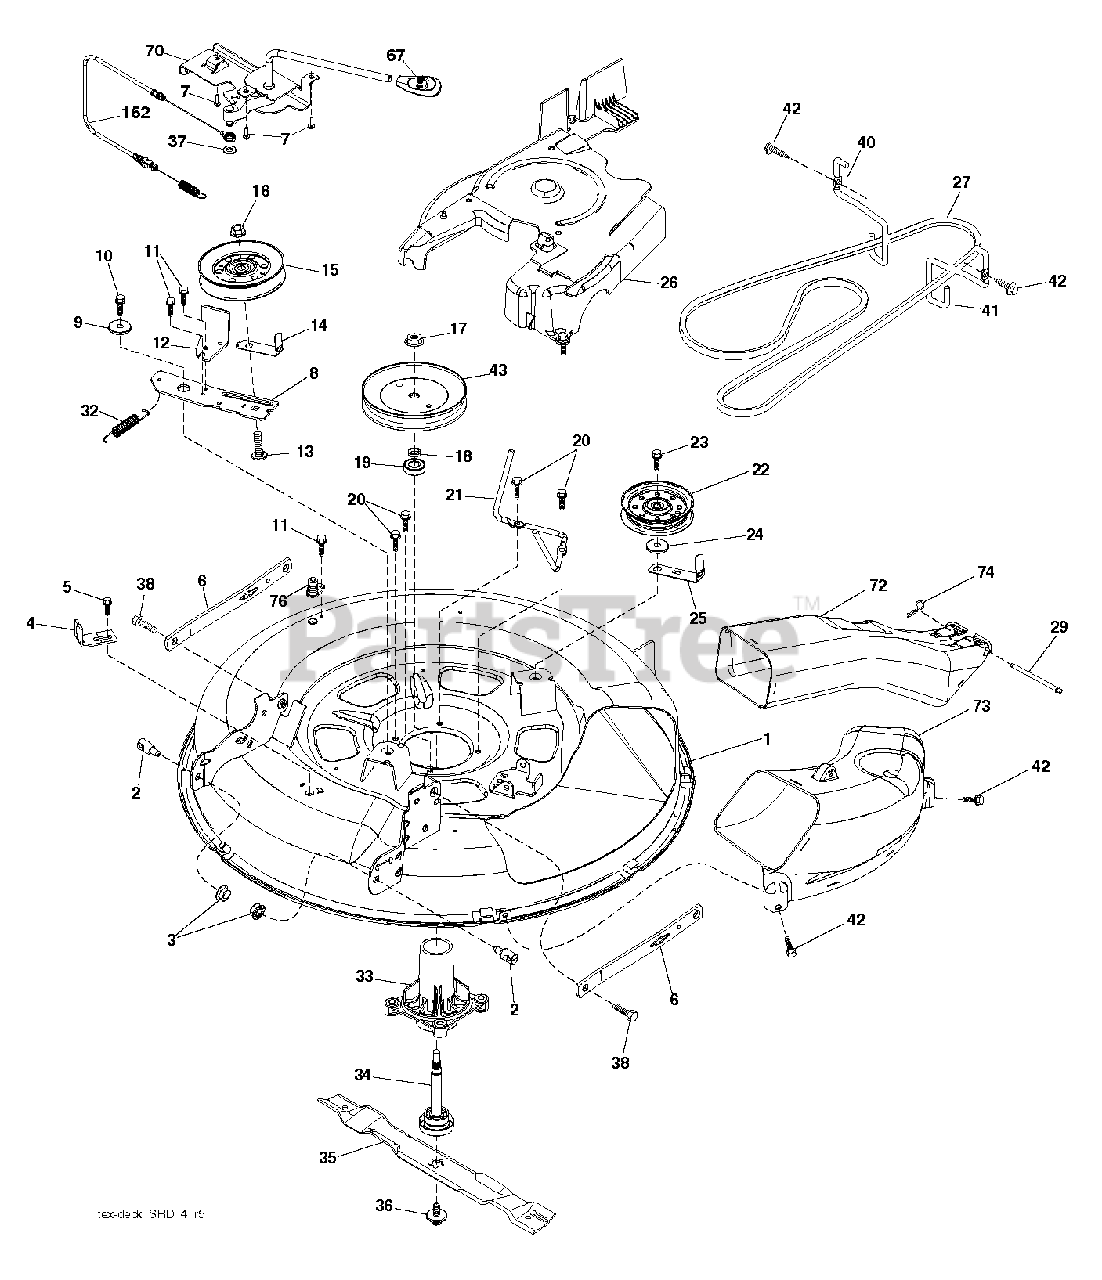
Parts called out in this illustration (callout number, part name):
2	STUD.FASTNER.W/ANTI-ROTATE
3	NUT LOCK HEX FLANGE 5/16-18
5	BOLT.5/16HEX.WHS.HD
6	ARMS.SUSP.MOWER.REAR.SRD
7	SCREW.#10 X 0.750.BOS THREAD
9	SPACER.RETAINER
10	SCREW 3/8-16X1
11	SCREW.1/4-20X5/8
12	ARM BRAKE MOWER RH
13	BOLT.3/8-16X1.50
14	KEEPER, BELT IDLER
15	PULLEY.IDLER.4.25
16	NUT LOCK FLG 3/8-16 UNC
17	NUT.FLANGE.LOCK.TOP
18	WASHER.SPACER.MANDREL
20	SCREW, WASHER HEAD
22	PULLEY.IDLER.FLAT.UNPLATED
23	SCREW LT
27	V-BELT.DRIVE.MOWER.30"
32	SPRING RETURN
33	HOUSING MANDREL
34	SHAFT.ASM.MDRL.N/GREASE.38
35	BLADE.MOWER.BAGGING.30"
36	BOLT.WASHER.ASM.7/16-2
38	BOLT.SHOULDER
42	SCREW, 3/8-16X3/4
43	PULLEY, MANDREL 6.5 PD
67	HANDLE.CLUTCH.CABLE.LT
70	CLUTCH.ASM.MANUAL.LT.PRED
74	RETAINER-SPRNG RB
76	PORT.WASHOUT
152	CABLE.CLUTCH.MANUAL.
